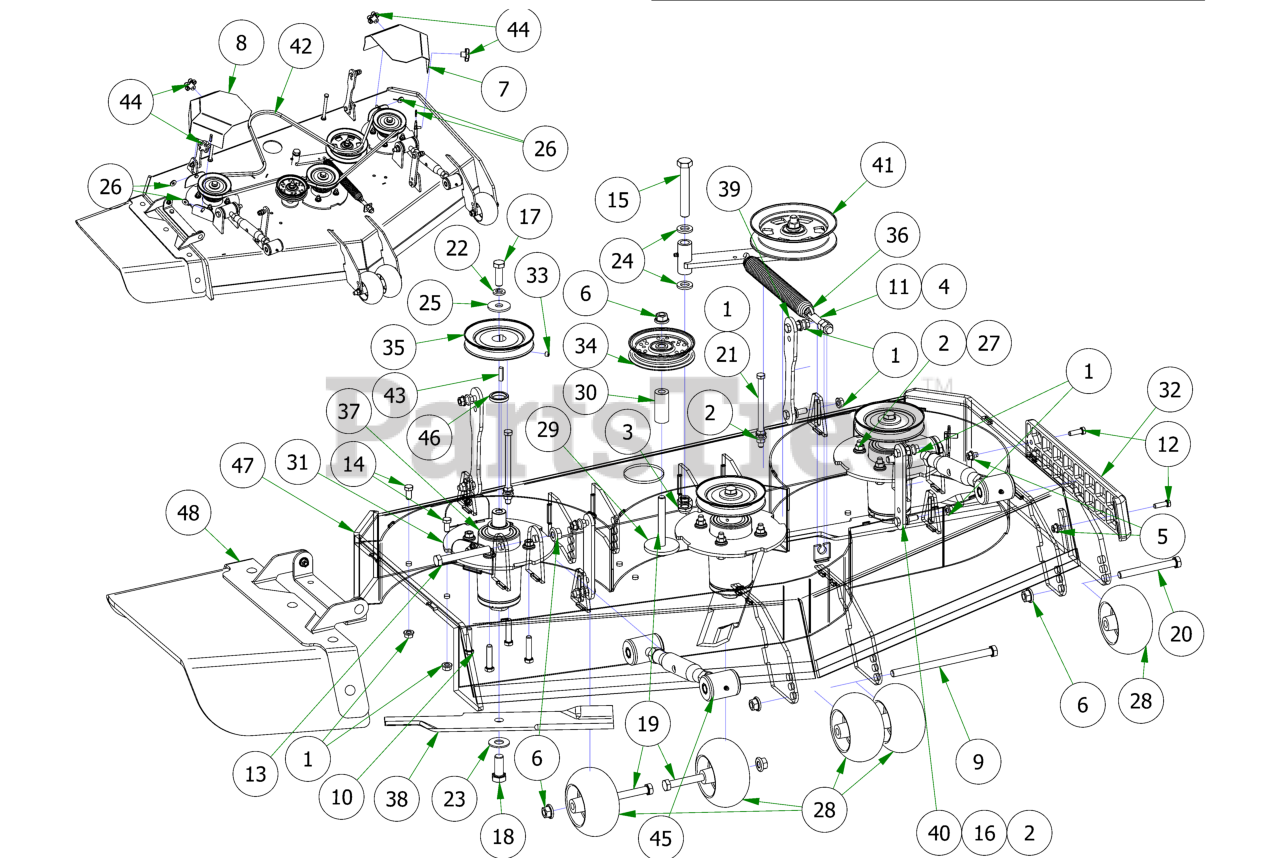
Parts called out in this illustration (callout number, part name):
1	3/8-16 HEX SERRATED FLANGE NUT HARD/ZINC
2	3/8-16 NYLON INSERT FLANGE LOCKNUT (GR.F) ZINC
3	5/8-11 NYLON INSERT JAM LOCKNUT ZINC
4	1/2-13 HEX NUT ZINC
5	5/16-18 NYLON INSERT FLANGE LOCKNUT ZINC
6	1/2-13 NYLON INSERT FLANGE LOCKNUT ZINC
7	2019 Stand On 48" Pulley Cover Trim
8	2019 Stand On 48" Pulley Cover Discharge
9	1/2-13 X 8 HEX CAP SCREW GR 5 ZINC
10	3/8-16 X 1-3/4 HEX C/S (GR.5) ZC
11	All Thread
12	5/16-18 X 1 HEX CAP SCREW (GR.5) ZINC
13	1/2-13 X 4 HEX CAP SCREW (GR.8) ZINC YELLOW
14	3/8-16 X 3/4 HEX CAP SCREW (GR.5) ZINC
15	5/8-11 X 4 HEX CAP SCREW (GR.8) ZINC YELLOW
16	3/8-16 X 1-1/2 HEX CAP SCREW (GR.5) ZINC
17	1/2-20 X 1-1/2 HEX CAP SCREW (GR.5) ZINC
18	5/8-18 X 1-1/2 HEX CAP SCREW (GR.8) ZINC YELLOW
19	1/2-13 X 4-1/4 HEX CAP SCREW (GR.5) ZINC
20	1/2-13 X 4-1/2 HEX CAP SCREW (GR.5) ZINC
21	3/8-16 X 5-1/2 HEX CAP SCREW (GR.5) ZINC
22	1/2 SPLIT LOCKWASHER (GR.8) ZINC/YELLOW
23	5/8 USS FLAT WASHER (1-3/4" OD) GR.8 ZINC YELLOW
24	.635 ID X 1.120 OD X .140 THICK FLAT WASHER NYLON
25	1/2 BELLEVILLE WASHER (1-5/8 OD X .140 THK) ZINC
26	.360 ID X .983 OD X .120 THICK FLAT WASHER NYLON BLACK
27	5/16 USS FLAT WASHER (7/8 OD) ZINC
28	2019 Deck Wheel
29	MZ Deck Idler Spacer
30	2019 Revolt Stationary Idle Spacer
31	Deck Spindle Support Plate
32	REVISED TRIM BUMPER_20180226
33	5/16-24 X 1/4 SOCKET SET SCREW (CUP PT) PLAIN
34	4 3/4 Idler Pulley - ABFI-76
35	5" Spindle Deck Pulley
36	2019 Outlaw Gen2 Deck Spring
37	Spindle Assembly
38	48" ZT/Mav/Compact Outlaw Blade with Fusion
39	2019 Stand-On Rear Deck Hanger
40	2019 Revolt Front Deck Hanger
41	2019 Revolt Deck Idler Assembly
43	1/4 X 1 SQ MACHINERY KEY 1018 STL PLN
44	5/16" Knob
45	Turnbuckle
46	Spacer, 1x1.375x.25
47	2019 48 Stand On Deck Weldment
48	2019 Outlaw Gen2 Chute Assembly
